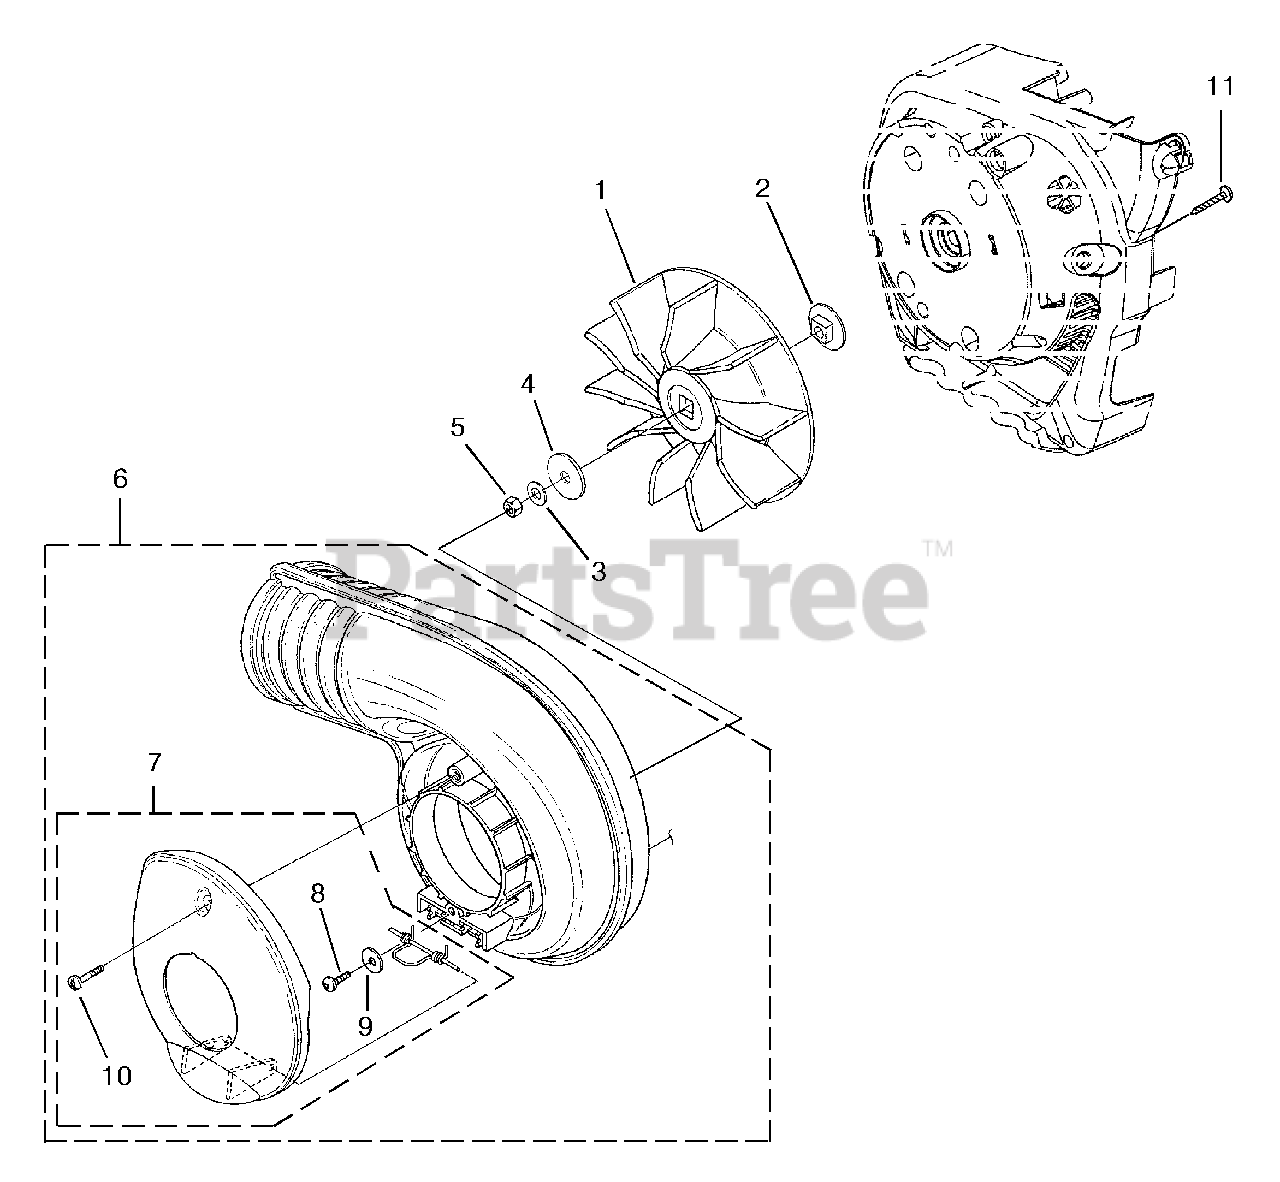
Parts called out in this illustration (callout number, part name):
1	Fan
2	Adapter, Fan
3	Washer, Belleville
4	Washer, Flat
5	Nut (3/8-24)
6	Volute W/Door Assembly
7	Volute Door
8	Screw, Thread Forming (10-14 X 1/2)
9	Washer
10	Screw, Machine (10-24 X 3/4)
11	Screw, Plastite (10-14 X 7/8)
